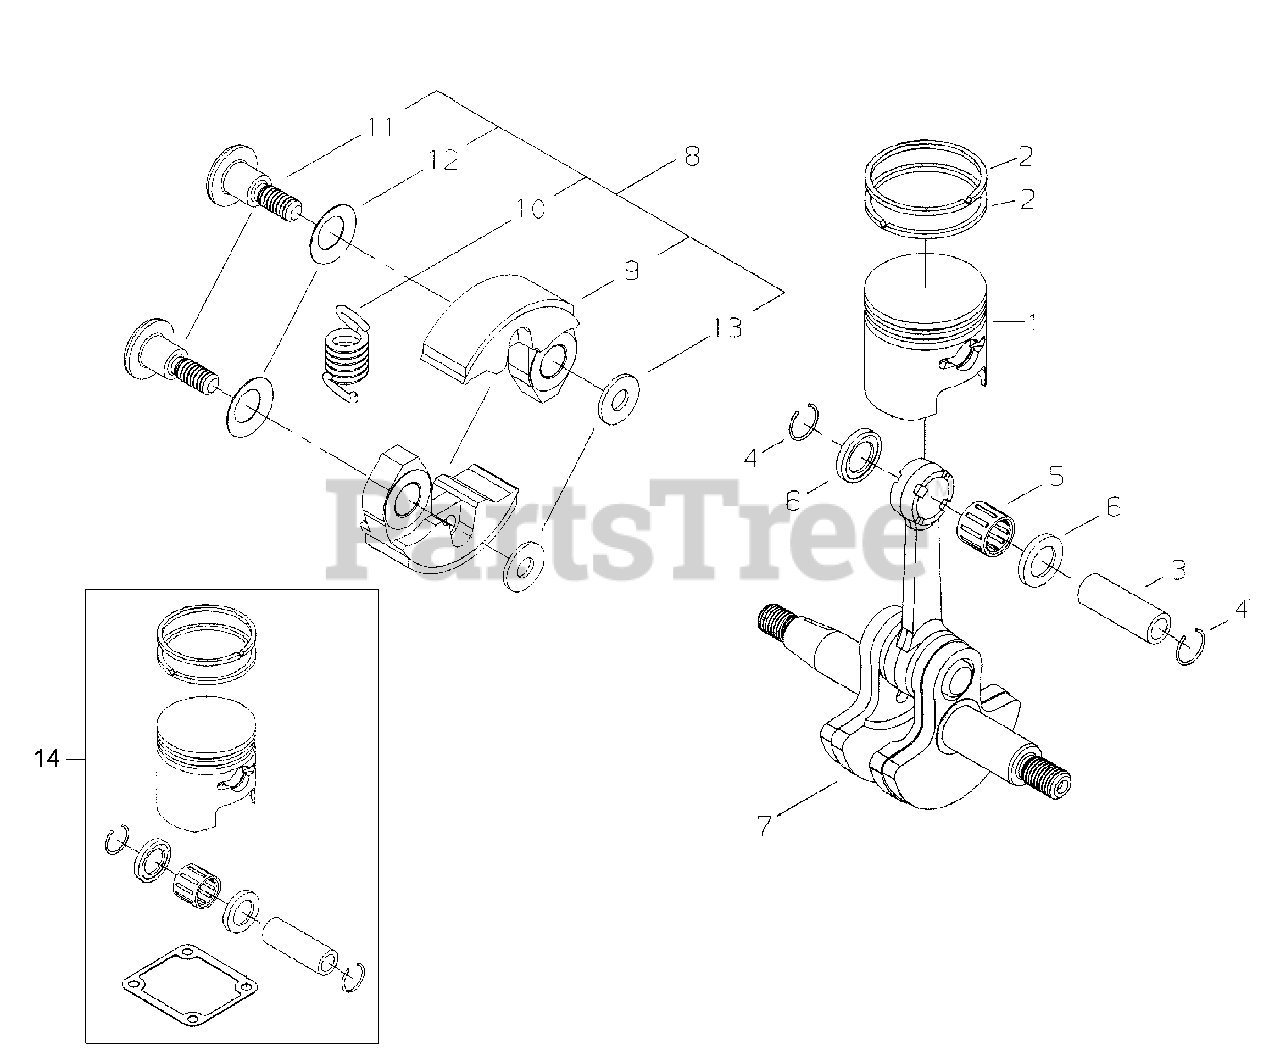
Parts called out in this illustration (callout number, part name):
1	PISTON
2	RING, PISTON
3	PIN, PISTON
4	RING, RETAINING
5	BEARING, NEEDLE
6	SPACER, PISTON
7	CRANKSHAFT ASSY
8	CLUTCH ASSY
9	SHOE, CLUTCH
10	SPRING, CLUTCH
11	BOLT, CLUTCH
12	WASHER - SPRING
13	WASHER - 6
14	PISTON ASSY
